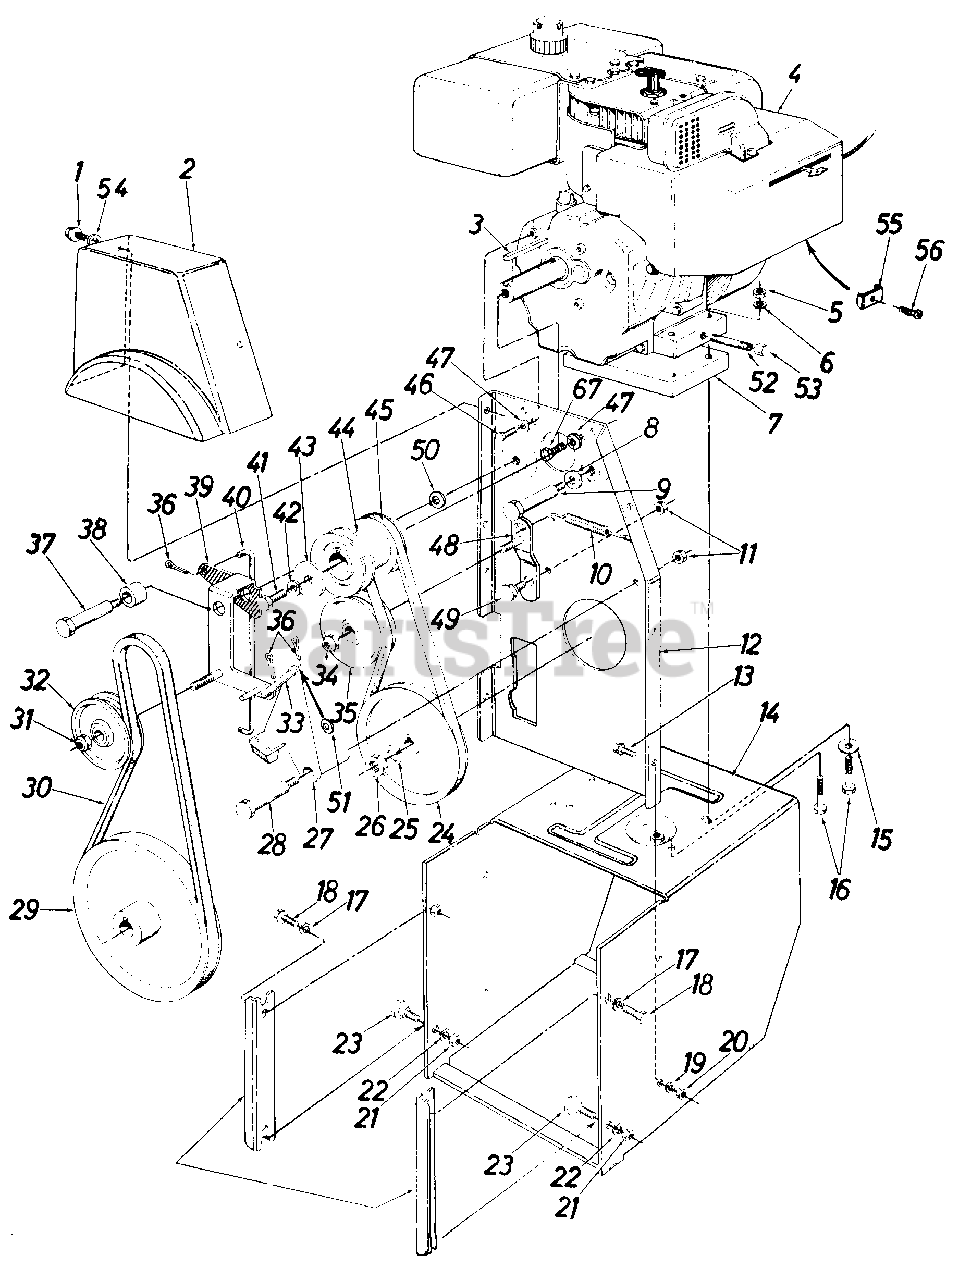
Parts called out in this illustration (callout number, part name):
1	Hex Wash. Self-Tap Scr. 5/16-24 x .50" Lg.
2	Belt Cover
3	Sq. Key 1/4" x 1.50" Lg.
4	Engine
5	Hex Nut 5/16-18 Thd.
6	L-Wash. 5/16" Scr.
7	Engine Spacer Ass'y.
8	Bell-Wash. .40 I.D. x .88 O.D.
9	Shld Scr. .498" Dia. x 3.00" Lg.
10	Ext. Spring .38 O.D. x 3.18" Lg.
11	Hex Cent. L-Nut 3/8-16 Thd.
12	Engine Brkt. Ass'y.
13	Hex Sems Scr. 5/16-18 x .75" Lg.
14	Frame Ass'y.
15	Fl-Wash. .345 I.D. x .75 O.D. x .060
16	Hex Scr. 5/16-18 x 2.50" Lg.
17	L-Wash. 3/8" Scr. H.D.
18	Pilot Scr. 3/8-16 x .88" Lg.
19	L-Wash. 5/16" Scr.
20	Hex Nut 5/16-18 Thd.*
21	Hex Nut 3/8-16 Thd.
22	L-Wash. 3/8" Scr. H.D.
23	Shld. Scr. .498" Dia. x .340" Lg.
24	V-Pulley .628 I.D. x 7.50 O.D.
25	L-Wash. for 5/8" Scr.
26	Hex Ins. Jam L-Nut 5/8-18 Thd.
27	Brake Brkt. Ass'y.
28	Shld. Scr. .498" Dia. x 2.00" Lg.
29	V-Pulley .875 I.D. x 10.12 O.D.
30	"V"-Belt 1/2" x 45.0" Lg.
31	Hex Ins. Jam L-Nut 3/8-24 Thd.
32	Fl-Idler w/Flanges 3.0 O.D.
33	Brake Linkage Ass'y.
34	Hex Ins. Jam L-Nut 3/8-24 Thd.
35	3.0" O.D. Fl-Idler w/Flanges
36	Int. Cot. Pin 5/16" Dia.
37	Shld. Scr. .625 Dia. x 2.750" Lg.
38	Spacer .75 O.D. x 1.00" Lg.
41	Hex Bolt 3/8-24 x 1.25" Lg.
42	L-Wash. 3/8" Scr. H.D.
43	Fl-Wash.
44	Engine Pulley-Double Groove
45	"V"-Belt 3/8 x 35.5 Lg.
46	Hex Scr. 5/16-24 x .62" Lg.
47	Bell-Wash. .345 I.D. x .88 O.D. x .060
48	Drive Idler Brkt. Ass'y.
49	Shld. Scr.-.625" Dia. x .170" Lg.
50	Bell-Wash. .40 I.D. x 1.12 O.D.
51	Fl-Wash. .34 I.D. x .750 O.D. x .05
52	Pipe Nipple-1/2" Pipe Thd. x 3.00" Lg.
53	Hex Scr. 1/4-18 Pipe Thd.
54	Fl-Wash. .340 I.D. x .62 O.D. x .62
55	Throttle Control Wire Clamp
56	Hex Sems Scr. #10-32 x .62" Lg.
